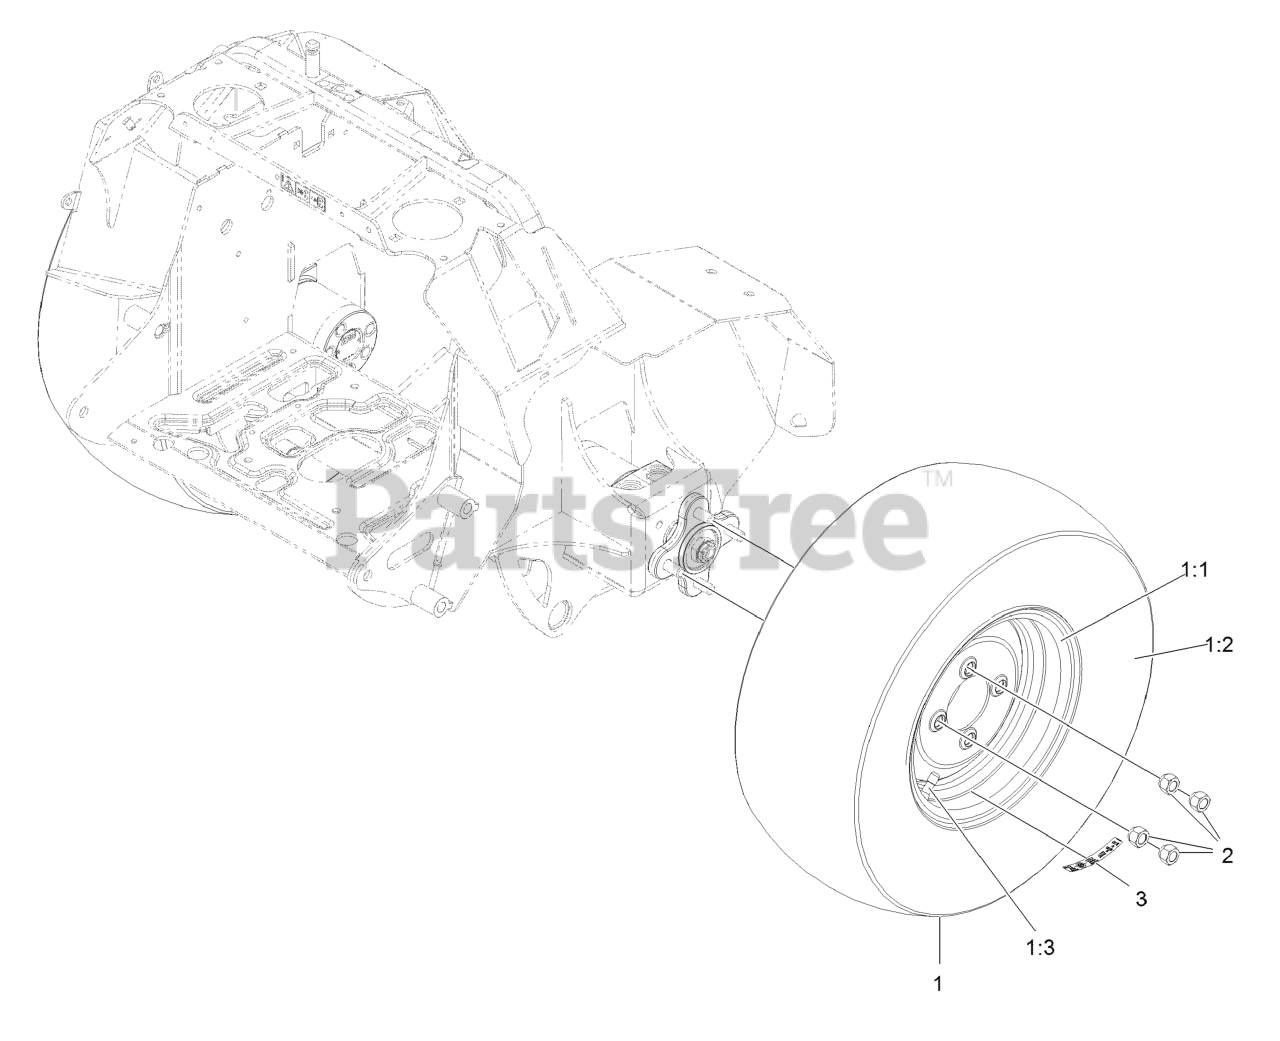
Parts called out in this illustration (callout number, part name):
1	ASM-WHL TIRE
1:1	WHEEL 10 X 6 WHT
1:2	TIRE-21X8.5-10
1:3	Stem-Valve
2	NUT-LUG
3	DECAL-TORQUE WHEEL LUG-HU
